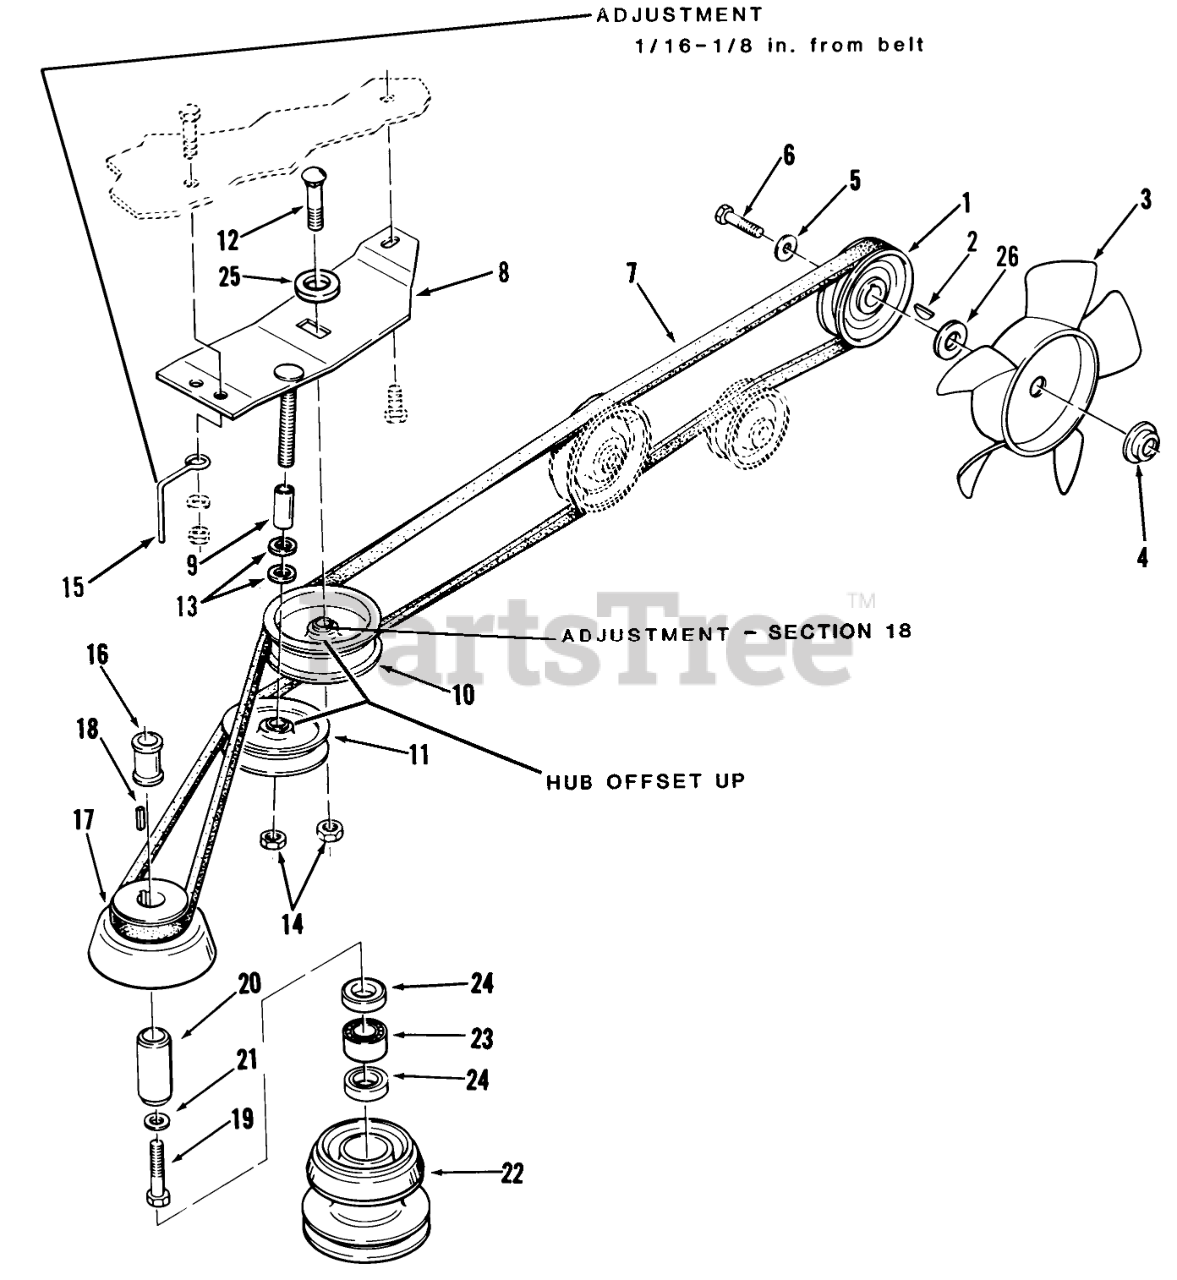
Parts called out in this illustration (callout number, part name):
1	PULLEY
2	KEY WOODR 1/8X1/2 DI
3	BLADE - FAN
4	SPACER FAN
5	WASHER
6	Bolt
7	V-BELT
8	ASSY PULLEY BRACK R
9	Spacer
10	Flat Idler
11	"V" Idler Pulley
12	Bolt
13	Washer
14	Nut
15	Belt Retainer
16	TUBE SPACER
17	PULLEY-ENGINE
19	HEX HD CAP SCREW
20	RACE BEARING
21	WASHER
22	Assy Pulley Mwr Dr
23	BRG-NEEDLE OPEN END
24	SEAL-OIL
25	Washer
26	Special Washer
